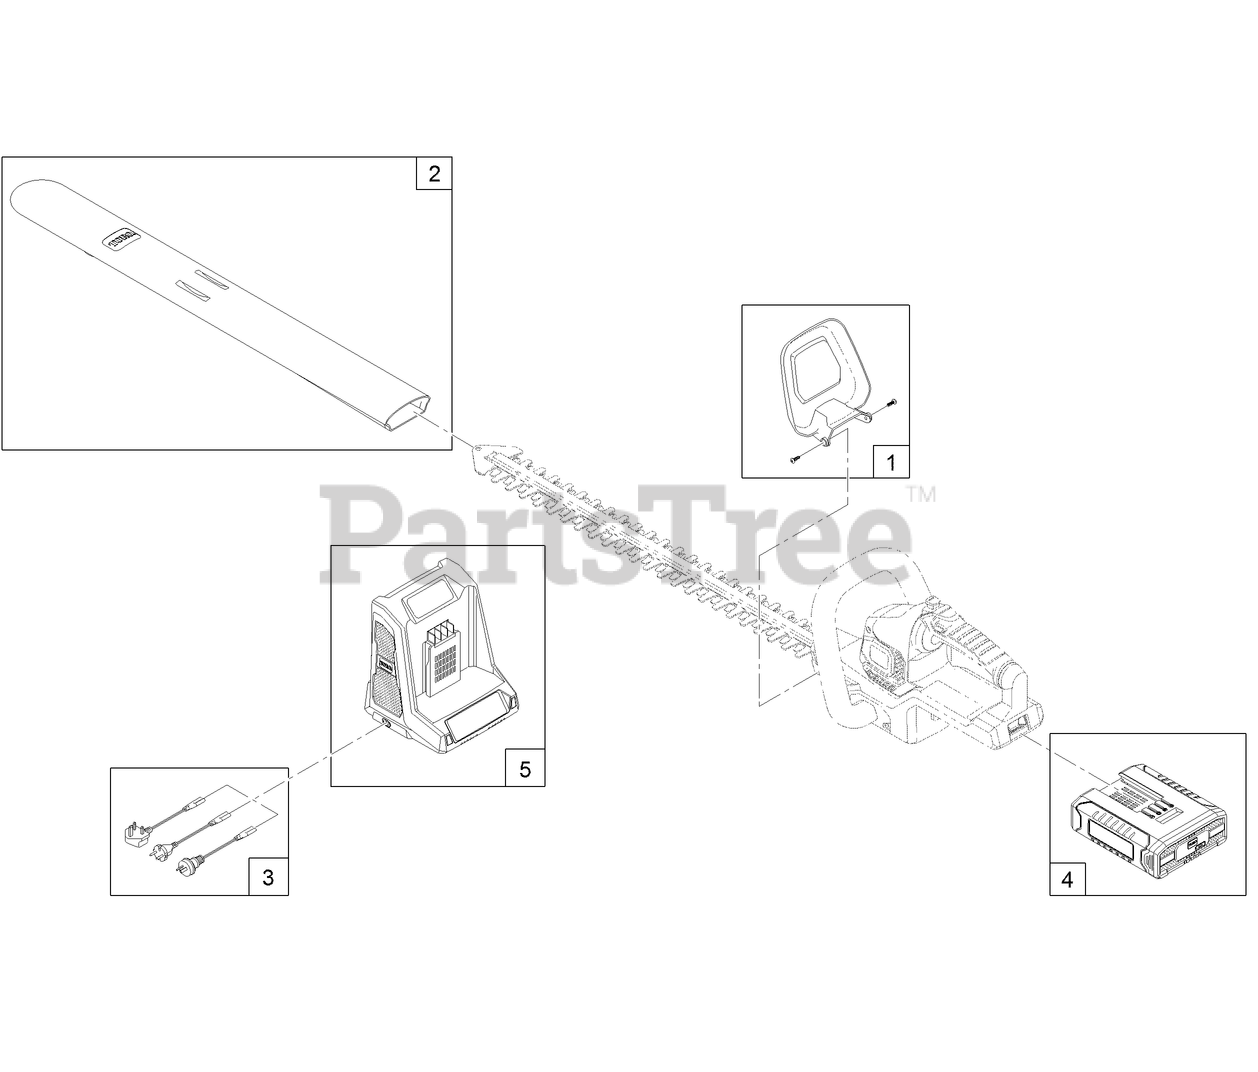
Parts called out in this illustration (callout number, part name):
1	GUARD-TRIMMER, HEDGE
2	SLEEVE-BLADE, HEDGE TRIMMER
3	CORD SET
4	BATTERY-40V MAX
5	CHARGER-BATTERY, 40V MAX
